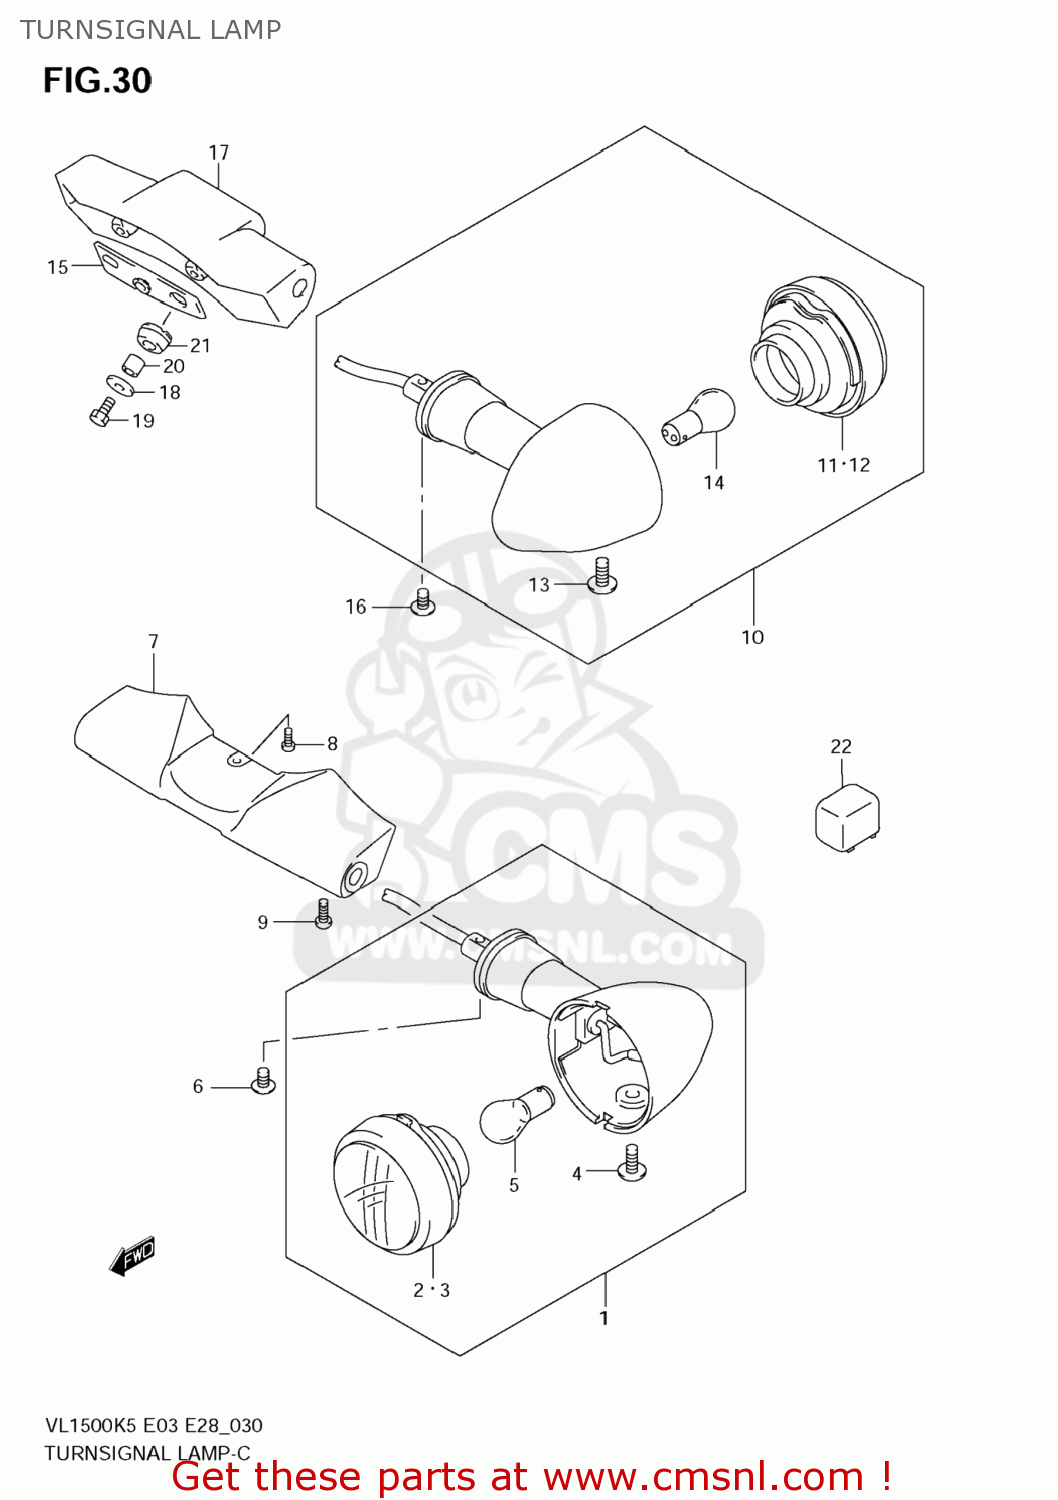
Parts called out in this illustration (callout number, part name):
1	LAMP ASSY,FR TURN SIGNAL,R
2	LENS
3	LENS
4	SCREW(4X10)
5	BULB(12V21/5W)
6	SCREW
7	STAY,FR TURNSIGNAL
8	SCREW(6X12)
9	SCREW(8X16)
10	LAMP ASSY,REAR
11	LENS
12	LENS
13	SCREW(4X10)
14	BULB(12V21W)
15	CUSHION,RR TURN STAY
16	SCREW
17	STAY,RR TURNSIGNAL
18	WASHER(6.5X20X1.2)
19	BOLT 6X20
20	SPACER(6.5X10X10)
21	CUSHION
22	RELAY ASSY,TURNSIGNAL LAMP
